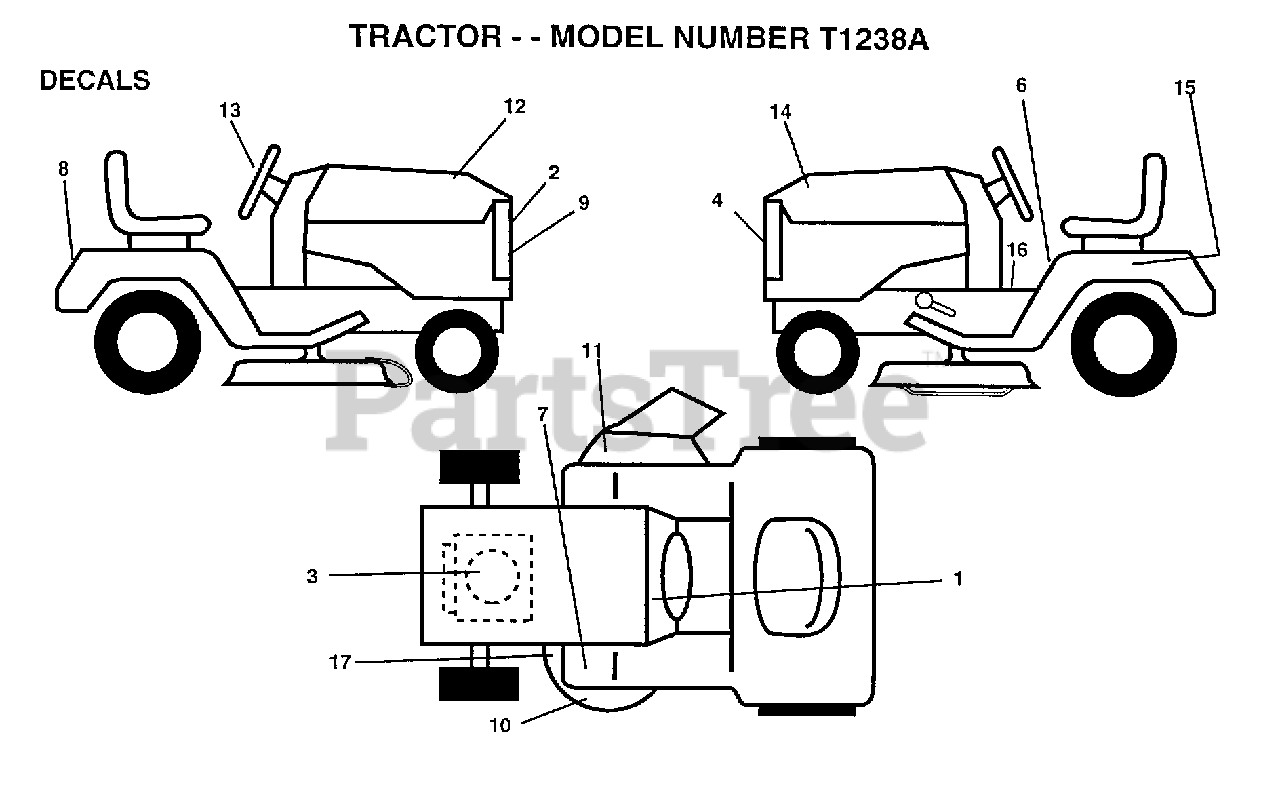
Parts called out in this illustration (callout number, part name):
1	DECAL.DASH.INSTR.
2	"DECAL,GRILL"
3	DECAL, HP ENGINE
4	DECAL GRILLE COOP
6	DECAL CAUTION
7	DECAL T
8	DECAL LOGO FENDER
9	DECAL.STRIPE.GR
11	"DECAL, WARNING"
12	DECAL HOOD RH
13	"DECAL,STR WHL T"
14	DECAL HOOD LH
15	DECAL.BTRY.DANGER
16	DECAL BRAK PARK
17	DECAL
